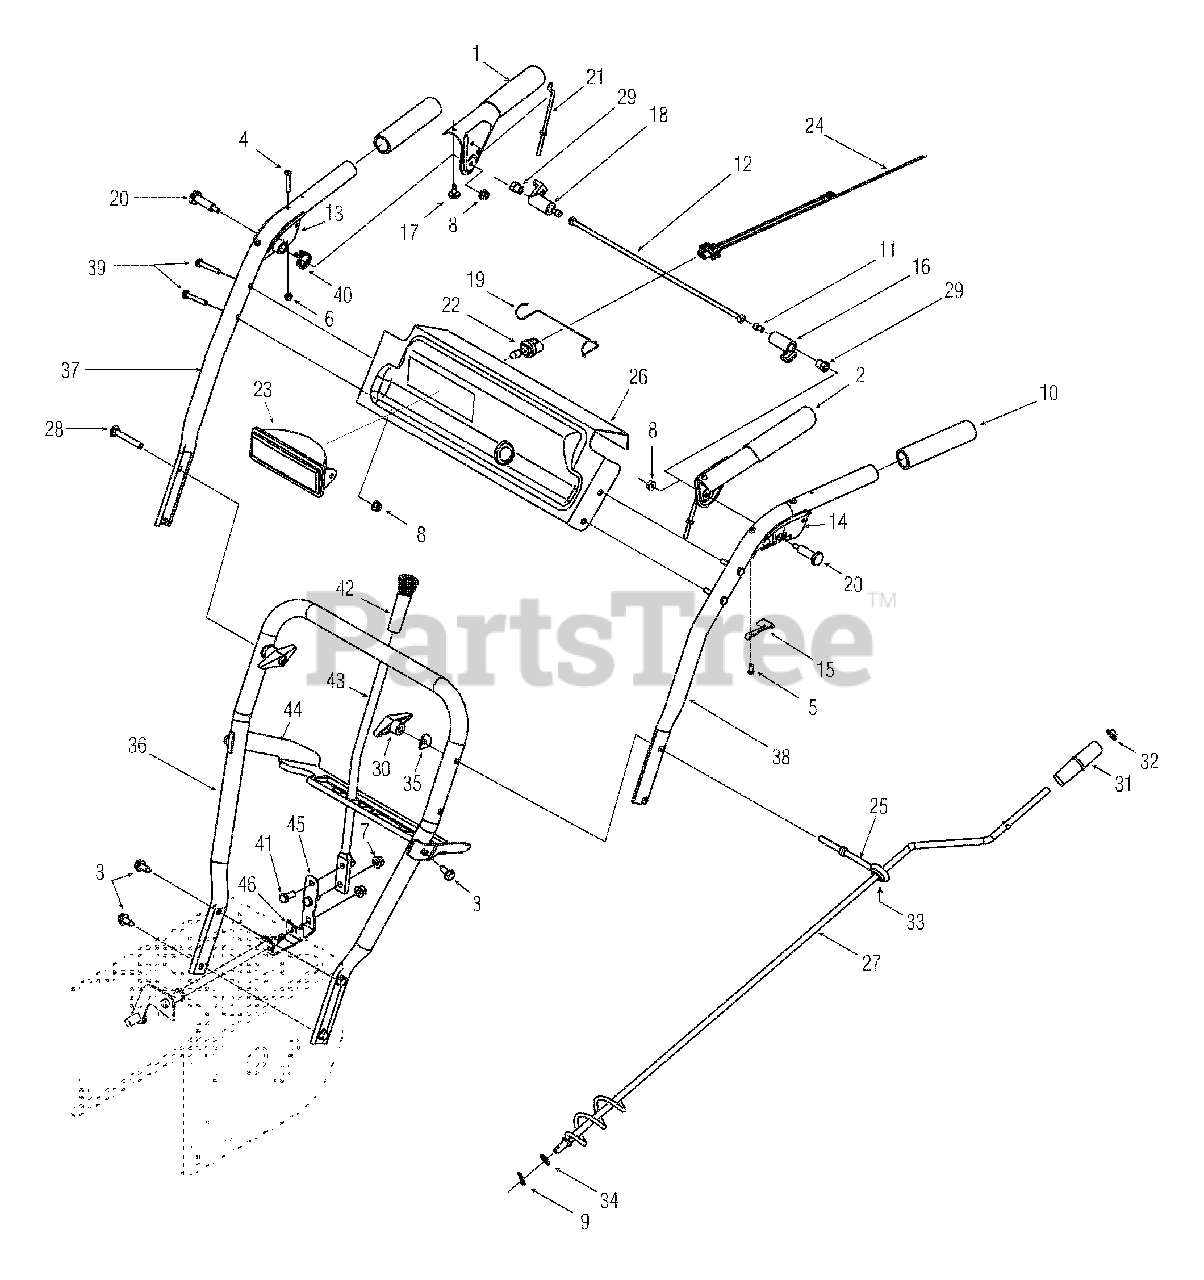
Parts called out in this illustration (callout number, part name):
1	Handle Ass'y, Engagement RH Black
2	Handle Ass'y, Engagement, LH Black
3	Screw, Self-tapping, 5/16-12, 0.750
4	Screw, Machine, #10-24, 1.375
5	Screw, #8-18 x .375
6	Nut, Hex Lock, #10-24, Gr2, Nylon
7	Nut, Flange Lock, 5/16-18, Grf, Nylon
8	Nut, Flange Lock, 1/4-20, Grf, Nylon
9	Pin, Cotter, .072 x 1.13
10	Grip, 1.0 ID x 5.0
11	Screw, 1/4-20, .375
12	Rod, Pivot
13	Handle, Clutch Lock, RH
14	Handle, Clutch Lock, LH
15	Spring, Control Lever Lock
16	Cam, Lock
17	Bumper, Rubber, .62 OD x .22
18	Plate, Lock
19	Retainer, Lens
20	Screw, Shoulder, .437 x 1.345, 1/4-20
21	Z Fitting, Cable
22	Lamp, Halogen, 12V, 27W
23	Lens Assembly, Lamp
24	Harness, Headlight
25	Eye Bolt, Chute Crank
28	Screw, Carriage, 5/16-18, 2.25, Gr5
29	Shoulder Nut, Hex, 1/4-20
30	Knob Assembly, Wing Nut, 5/16-18
31	Crank Knob, 1.0 Diameter x 3.2, Black
32	Cap, Push, 3/8 Rod
33	Grommet, .44 ID x .94 OD x .50
34	Washer, Flat, .375 x .738 x .063
35	Washer, Saddle, 320 x .93 x .060
39	Screw, Hex, 1/4-20 x 1.5
40	Spring, Torsion, .8156 x .3038
41	Screw, 5/16-18 x 1.0
44	Panel, Speed Selector (5 FW, 2 RV)
45	Spring, Shift Lever
46	Bracket, Shift Spacer
